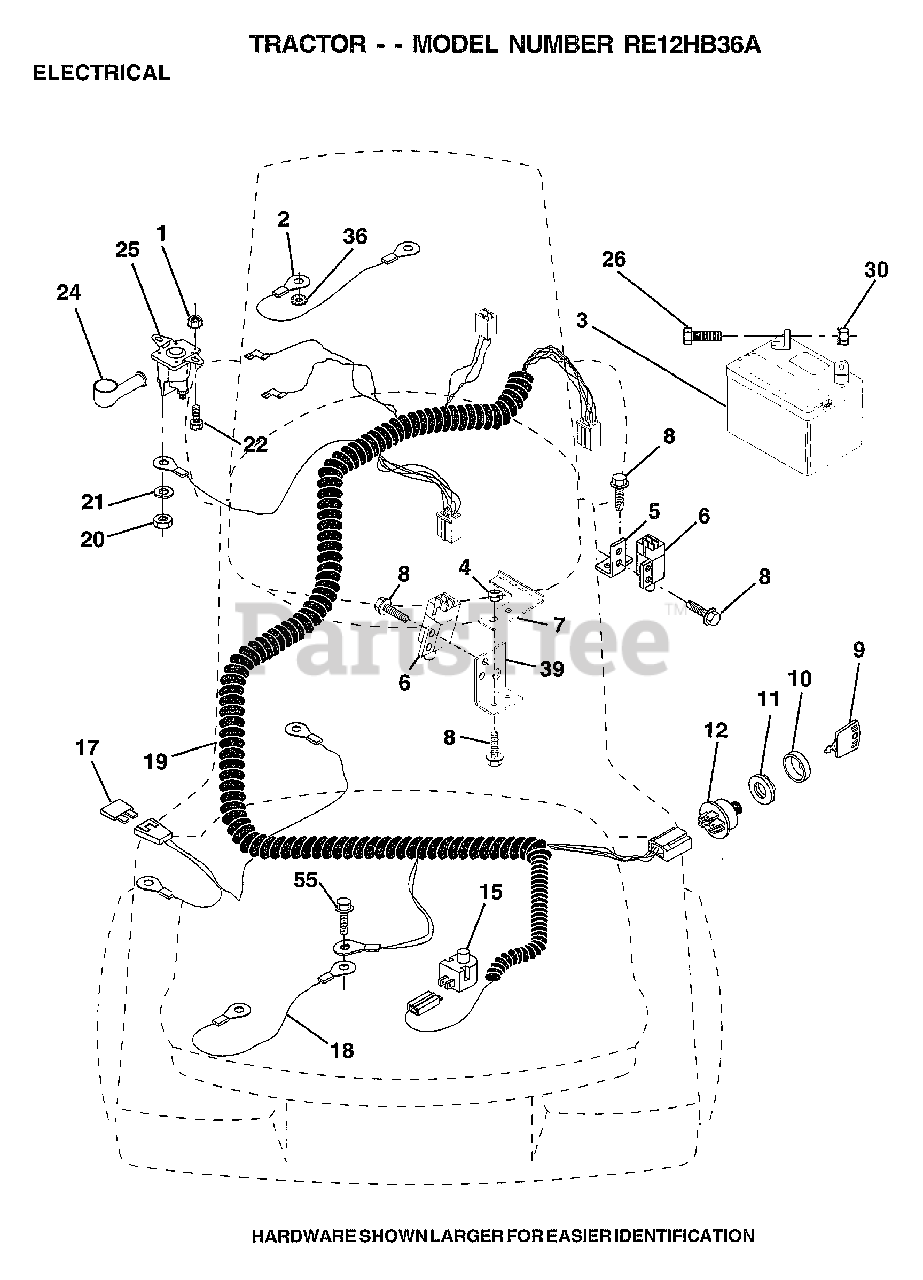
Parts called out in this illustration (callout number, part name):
1	NUT HXKEP 1/4X20
2	CABLE ASM.
4	LOCKNUT
5	BRACKET LT
6	SWITCH INTERLOCKT
7	KEEPER.ACTUAT.LR.
8	SCREW
9	KEY MLD GEN DELTA
10	COVER KEY SWITCH
12	SWITCH.IGNITION
15	SWITCH SEAT
17	FUSE.15 AMP
18	CABLE ASSY
19	HARNESS, IGNITION
20	NUT
22	BOLT HXHD FIN
26	BOLT LT
30	NUT
36	LOCKWASHER
39	BRACKET SWT CLUTC
55	SCREW LT
